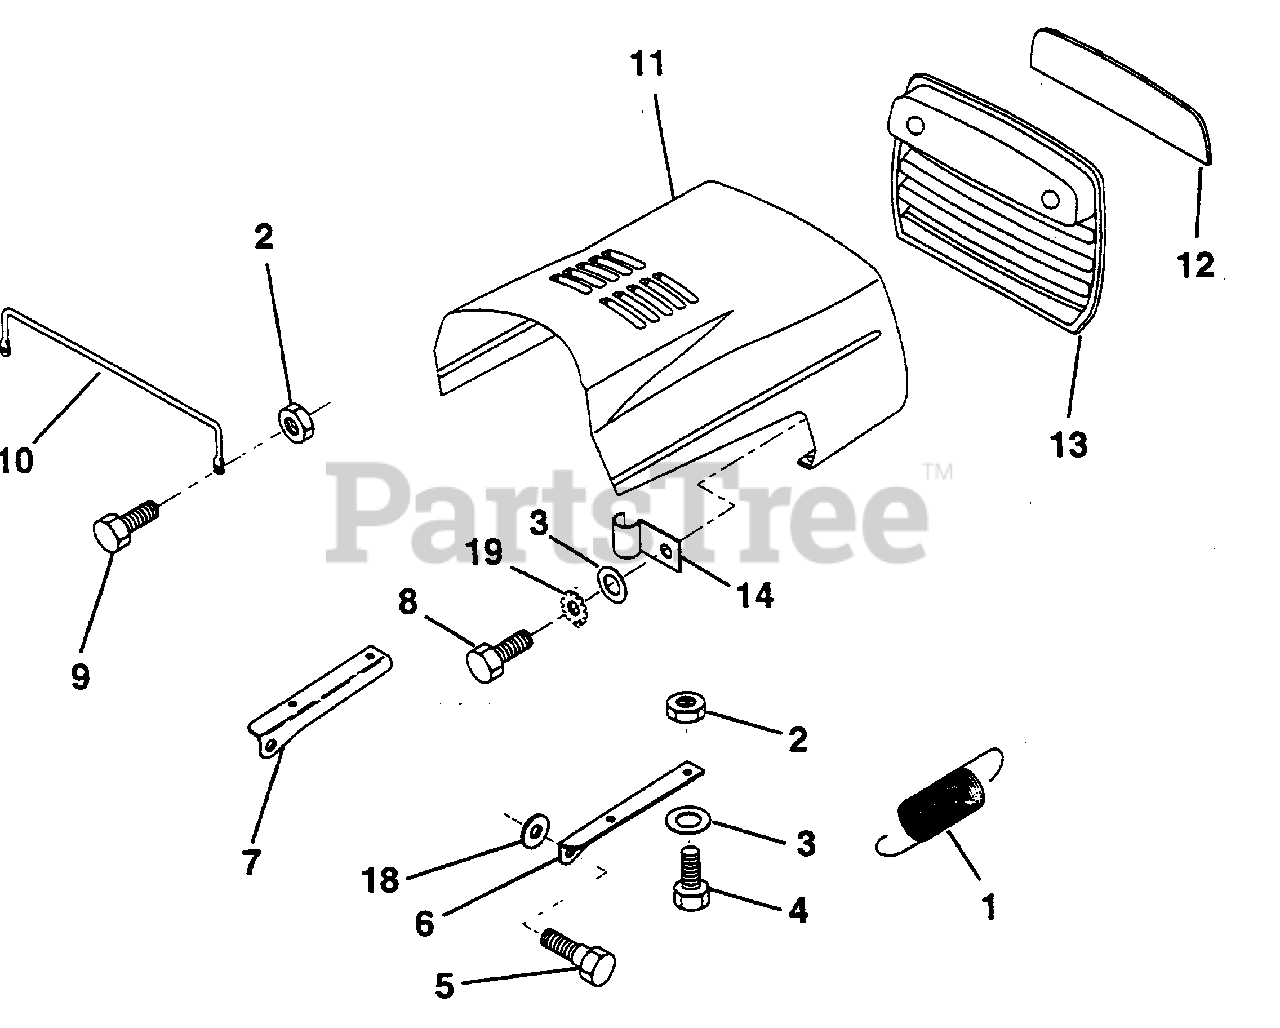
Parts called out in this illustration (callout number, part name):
1	Spring, Extension (AYP part number)
2	Nut, Hex, Keps 1/4-20 (AYP part number)
3	Washer 9/32 x 5/8 x 16 Gauge (AYP part number)
4	Bolt, Hex Head, Fin. 1/4-20 UNC x 5/8 Grade 5 (AYP part number)
5	Bolt, Shoulder (AYP part number)
6	Bracket, Hood, R.H. (AYP part number)
7	Bracket, Hood, L.H. (AYP part number)
8	Screw, Hex Head, Fin. #13-16 Hi-Lo x 5/8 (AYP part number)
9	Bolt, Hex Head, Fin. 1/4-20 x 3/4 Grade 5 (AYP part number)
10	Brace, Hood (AYP part number)
11	Hood (AYP part number)
12	Lens Headlight Bar (AYP part number)
13	Grill (AYP part number)
14	Clip Fuel Line (AYP part number)
18	Washer 11/32 x 11/16 x 16 Gauge (AYP part number)
19	Washer, Lock, Internal/External Tooth 1/4 (AYP part number)
